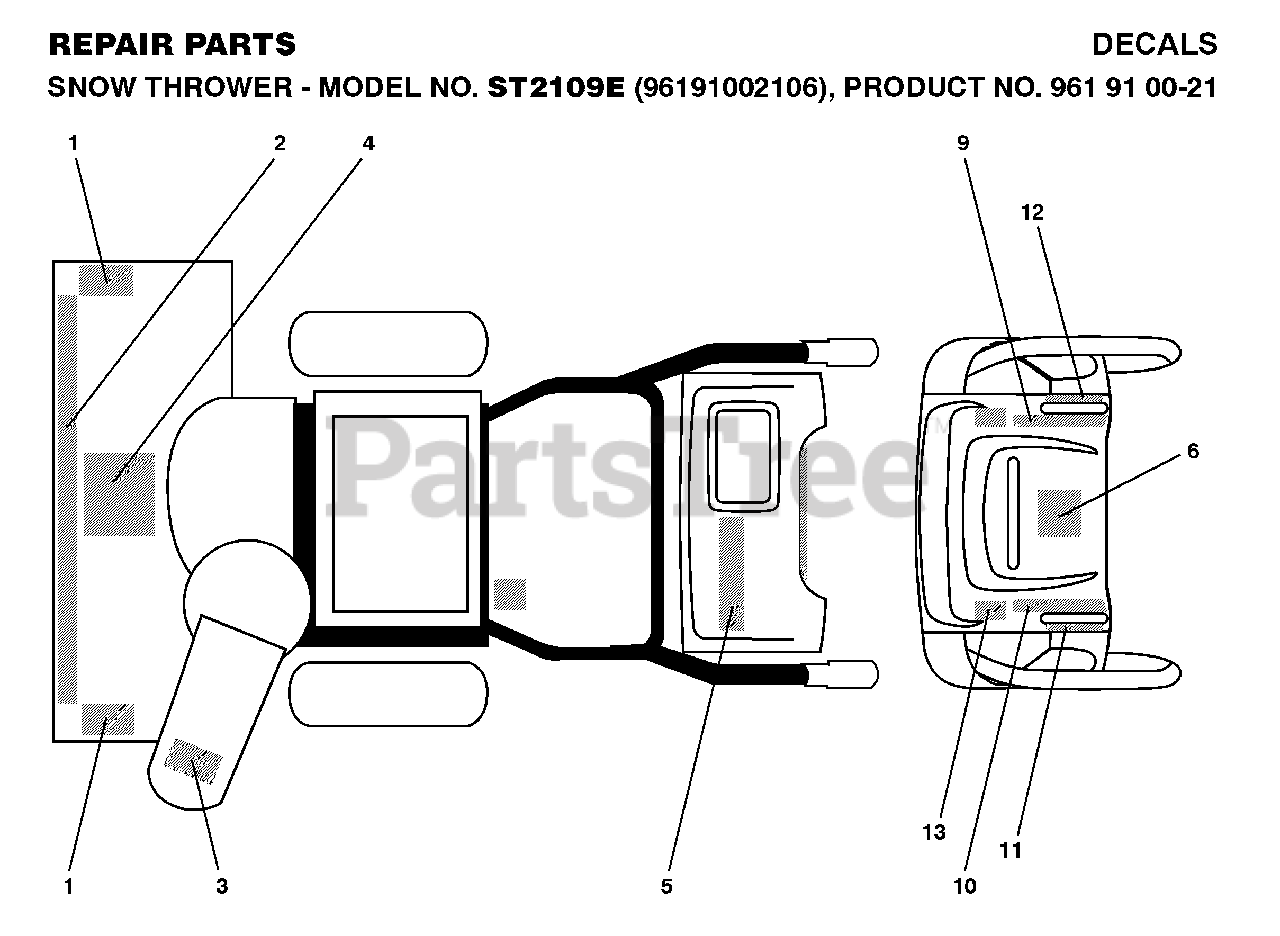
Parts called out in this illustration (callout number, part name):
1	DECAL.AUGER.SAFETY.
3	DECAL.CHUTE.SAFETY.
4	DECAL.AUGER."
6	DECAL.CONSOLE.INSTRUCTION
10	DECAL.REM.DEFLECTOR.LT
11	DECAL.POWER.STEER.LT.TRIG.INT
12	DECAL.POWER.STEER.RT.TRIG.INT
